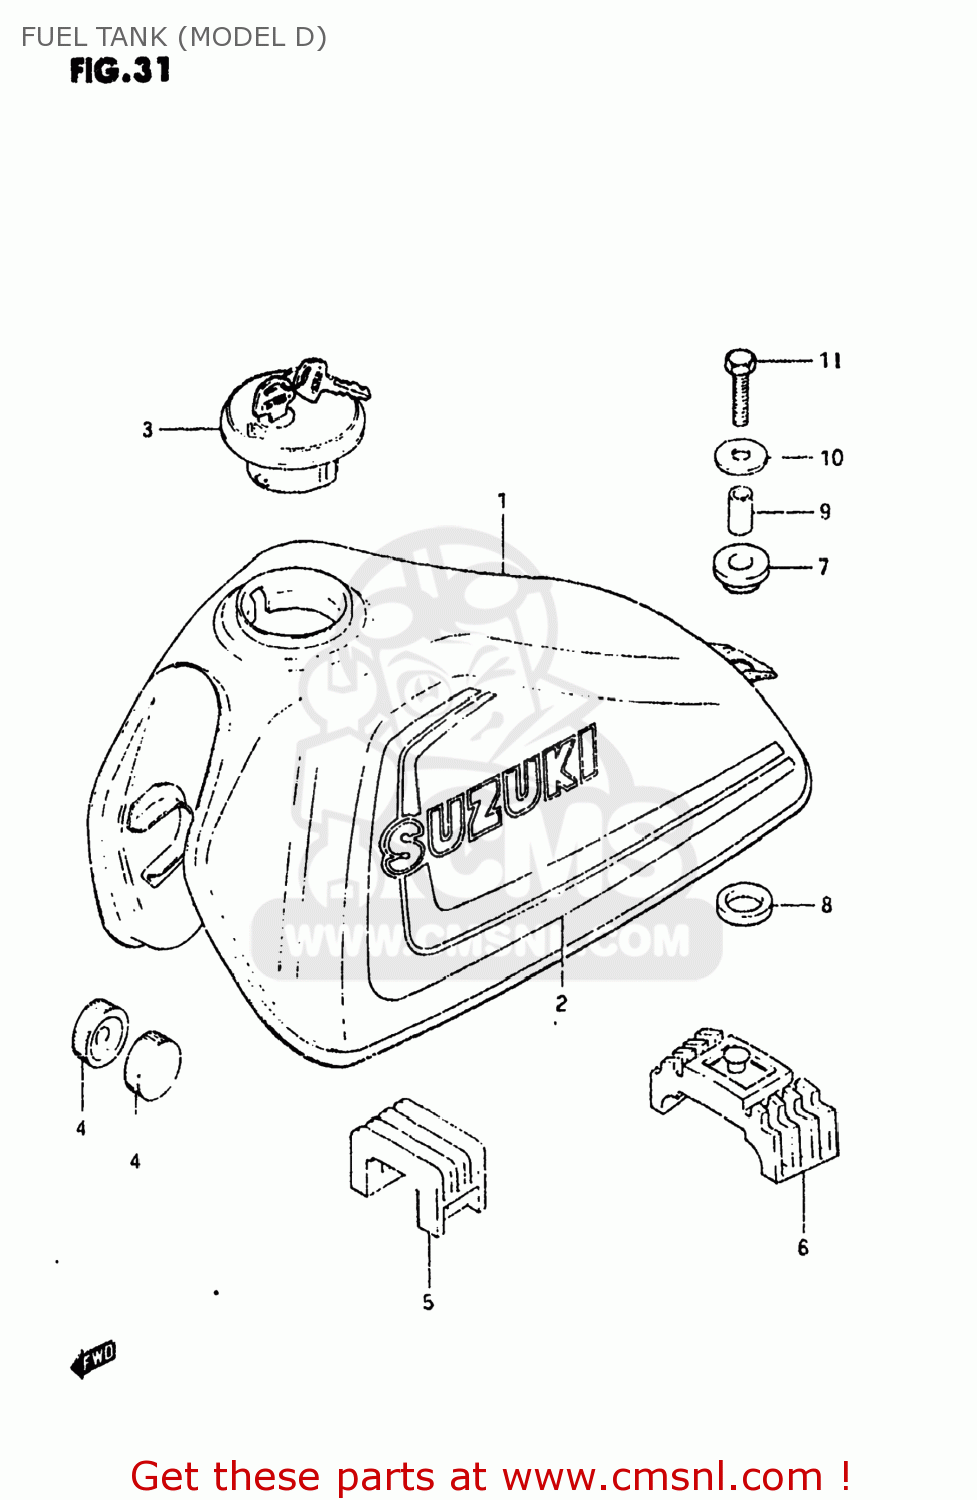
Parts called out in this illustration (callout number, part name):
1	TANK ASSEMBLY,FUEL
3	CAP SET,FUEL TANK
4	CUSHION
5	CUSHION,TANK UPR FR
6	CUSHION,FUEL TANK,REAR
7	CUSHION
8	CUSHION
9	SPACER(8.5X12X19)
10	WASHER (8.5X29X1.6)
11	BOLT (8X30)
